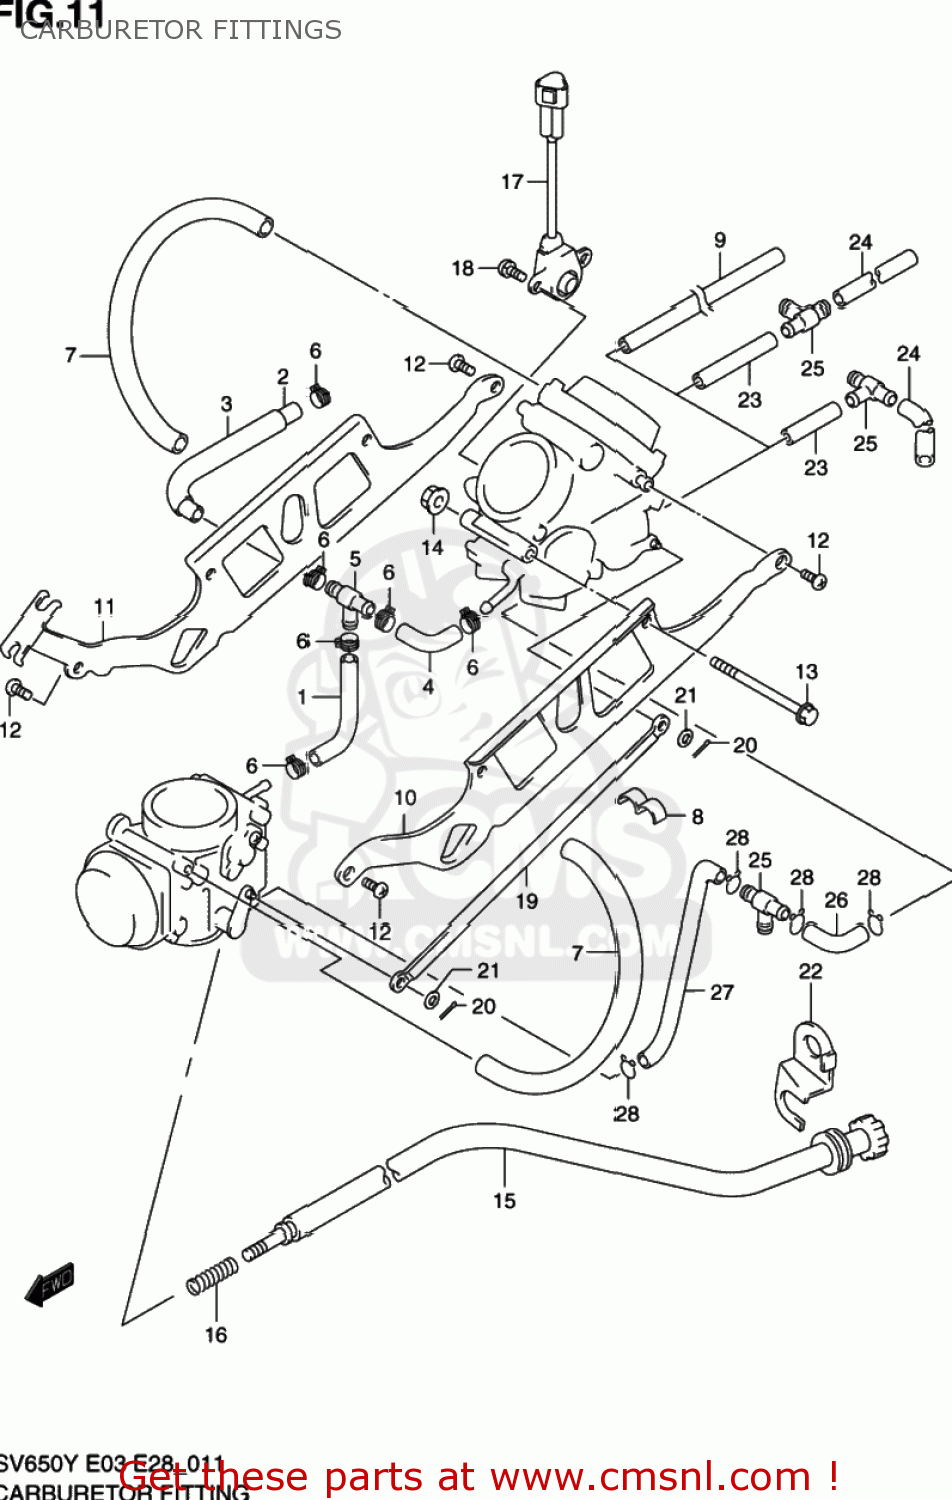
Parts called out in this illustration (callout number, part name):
1	HOSE
2	HOSE(5.3X10.5X125)
3	HOSE(11X15X70)
4	HOSE,5.3X10.5
5	NIPPLE
6	CLIP
7	HOSE(7X11X250)
8	CLIP
9	HOSE(5X9X600)
10	PLATE
11	PLATE
12	SCREW
13	BOLT
14	NUT
15	SCREW,ADJUST
16	SPRING
17	SENSOR ASSY
18	SCREW
19	LEVER ASSY
20	PIN
21	WASHER,STARTER SHAFT
22	PLATE,IDLE ADJUST
23	HOSE (5X9X60)
24	HOSE(5X9X600)
25	NIPPLE
26	HOSE,5.3X10.5
27	HOSE(5.3X10.5)
28	CLIP
